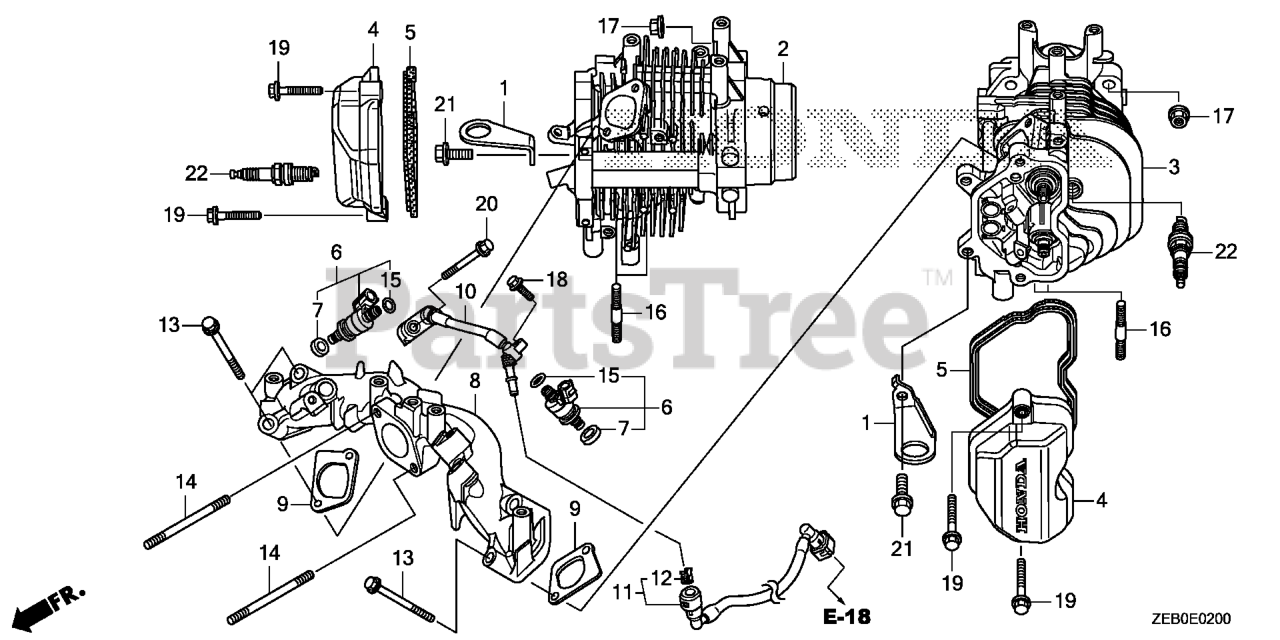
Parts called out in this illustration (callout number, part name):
1	HANGER, ENGINE
2	CYLINDER HEAD (#1)
3	CYLINDER HEAD (#2)
4	COVER, CYLINDER HEAD
5	GASKET, HEAD COVER
6	INJECTOR ASSY., FUEL
7	RING, SEAL
8	MANIFOLD, IN.
9	GASKET, IN. MANIFOLD
10	HOSE A, FUEL
11	HOSE B, FUEL
13	BOLT, FLANGE (8X55)
14	BOLT, STUD (6X85)
15	O-RING (6.3X2.2)
16	BOLT, STUD (8X22)
17	NUT, FLANGE (10MM)
18	BOLT, FLANGE (6X22)
19	BOLT, FLANGE (6X30)
20	BOLT, FLANGE (6X35)
21	BOLT, FLANGE (8X16) Use from Engine SN 1000016.
22	SPARK PLUG (BPR5ES) (NGK)
